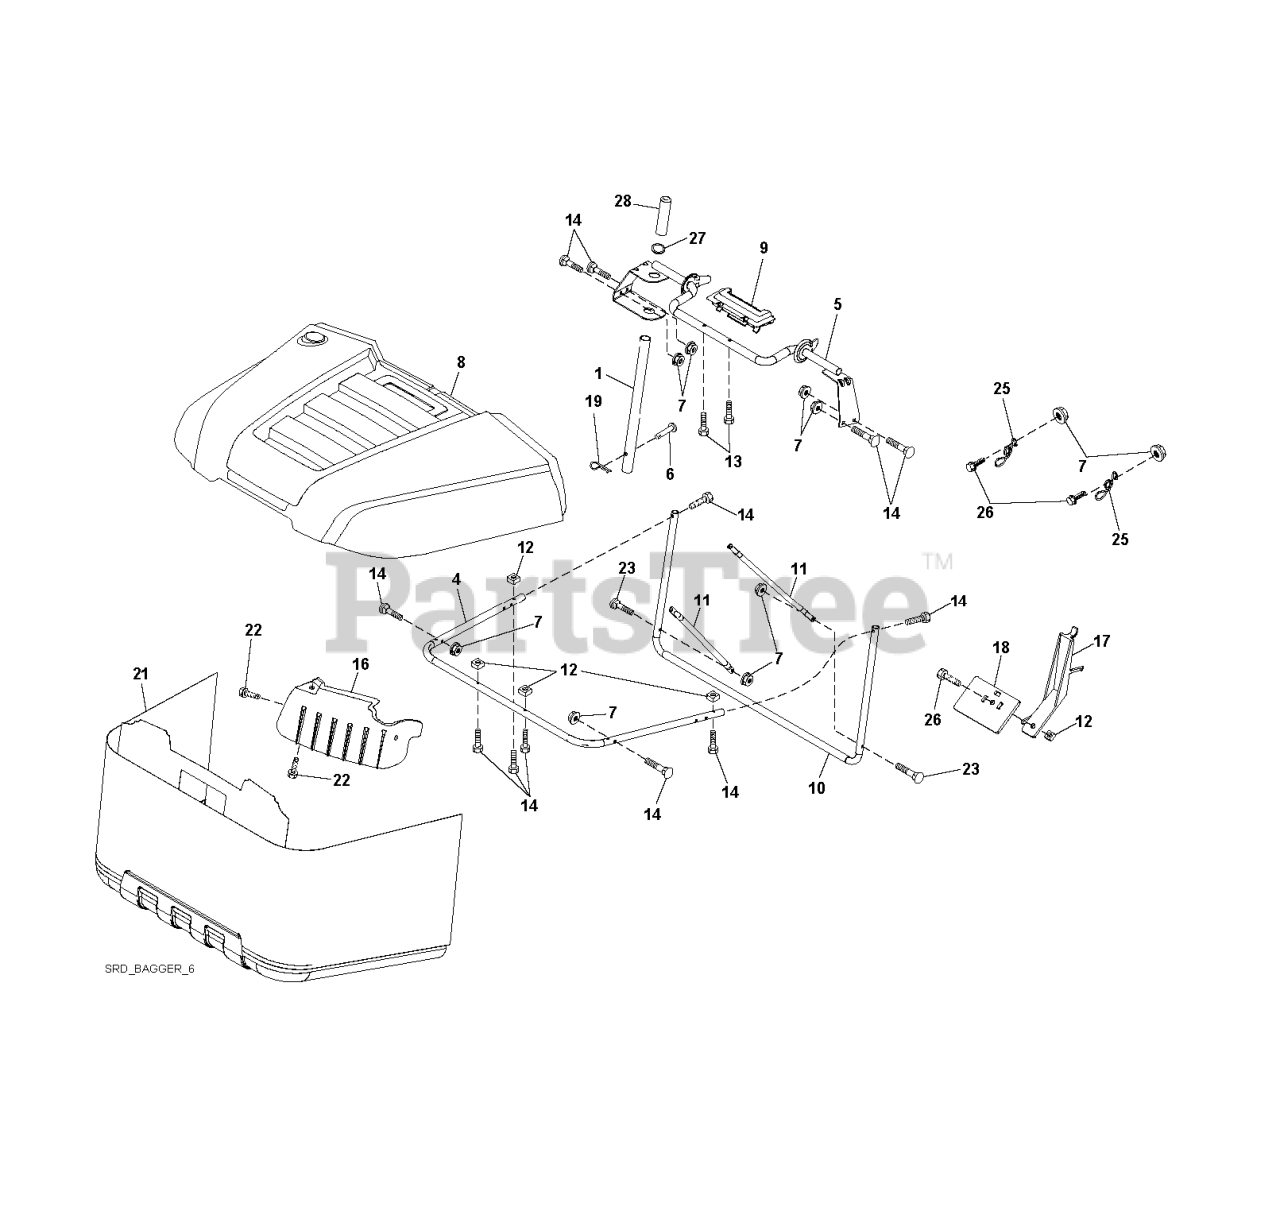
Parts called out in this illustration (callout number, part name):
1	TUBE HANDLE
4	Frame Asm Bagger Top
5	FRAME.ASM.TOP.BAGGER.SRD
6	RIVET,DRILLED
7	NUT T
8	BAGGER.TOP.SUB.ASSEM.SRD
9	INSERT.HANDLE.BAGGER.(2 2)
10	FRAME.FRONT.SRD.BAGGER
11	TUBING.BRACE.BAGGER.SRD.BLACK
12	NUT.SQUARE.1/4
13	SCREW.1/4X1.150.HXWSH
14	BOLT.SHOULDER.HX.WSH.1/4X1.150
16	DEFLECTOR.BAGGER.SRD
17	LEVER.BAGGER.FULL.SRD.BLACK
18	PADDLE.BAGGER.FULL.SRD.BLACK
19	RETAINER M
22	SCREW.HI-LO.CONSOLE
25	SPRING.LATCH.BAGGER.SRD
26	SCREW HEX CRT
27	RB GROMMET.RUBBER.SRD
28	GRIP.HANDLE.BLACK
